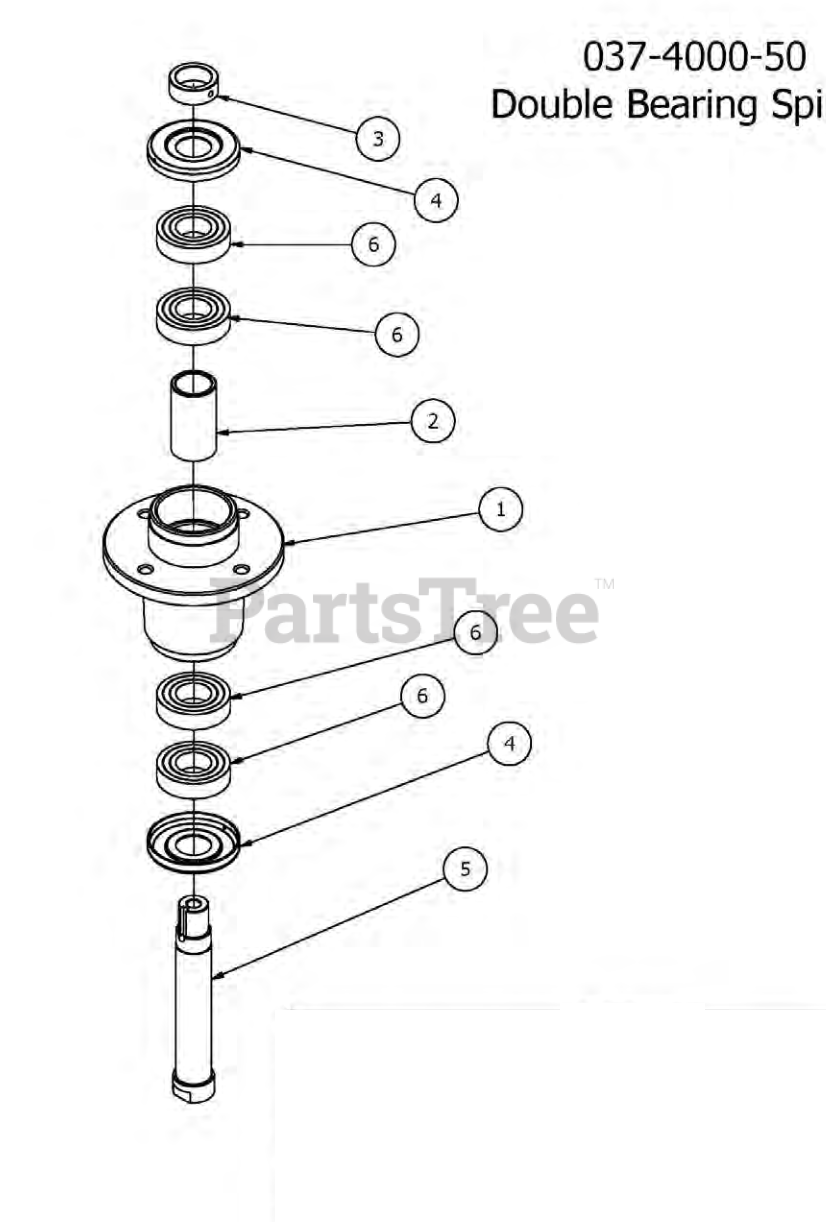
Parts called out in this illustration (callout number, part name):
1	4000 Series Spindle Housing
2	4000 Series Spindle Spacer
3	Locking Collar w/ 1/4"-20 Set Screw
4	Spindle Dust Cap
5	ZT-AOS Spindle Shaft
6	Bearing-6206
